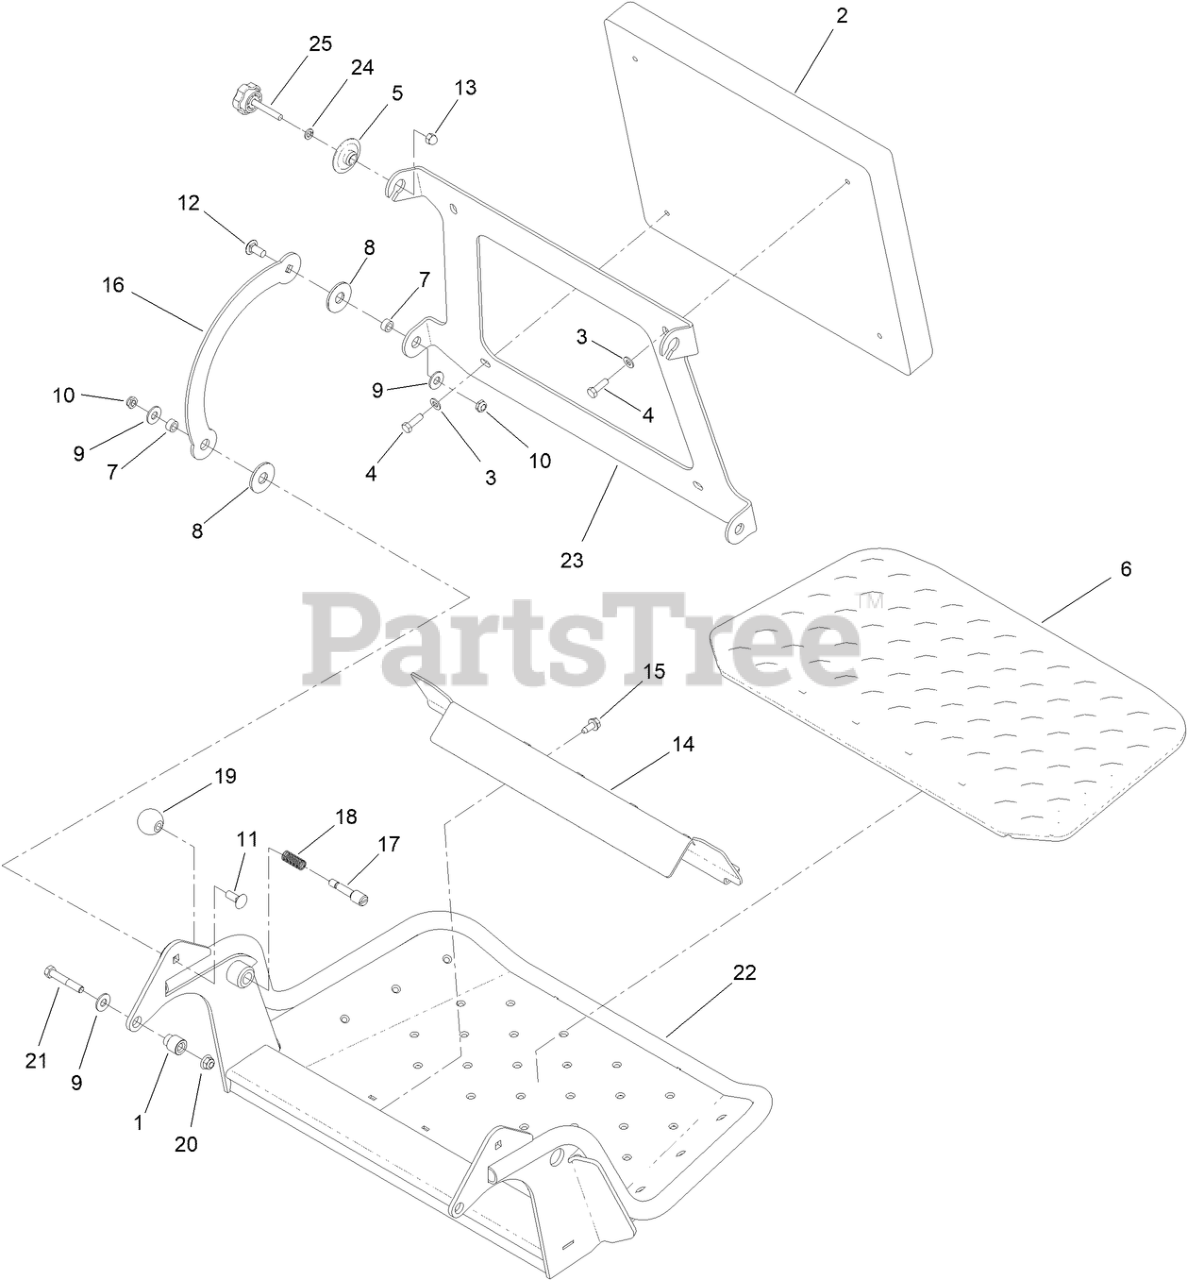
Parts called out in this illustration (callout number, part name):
1	BUSHING-FLANGED
2	PAD-CUSHION
3	WASHER-PLAIN
4	SCREW-HH
5	SLIDE-BUSHING
6	MAT-PLATFORM
7	SPACER
8	WASHER-FRICTION, COMPOSITE
9	WASHER-FLAT
11	BOLT-CARR
12	SCREW-CARR
13	NUT-ACORN
14	CLAMP-SHIELD
15	SCREW-HWHTF
16	LINK-PAD
17	PIN-LATCH
18	SPRING
19	KNOB-BALL
20	NUT-HF, NI
21	SCREW-HH
22	PLATFORM ASM
23	HINGE-PAD
24	WASHER-LOCK
25	BOLT-TAP, HH
